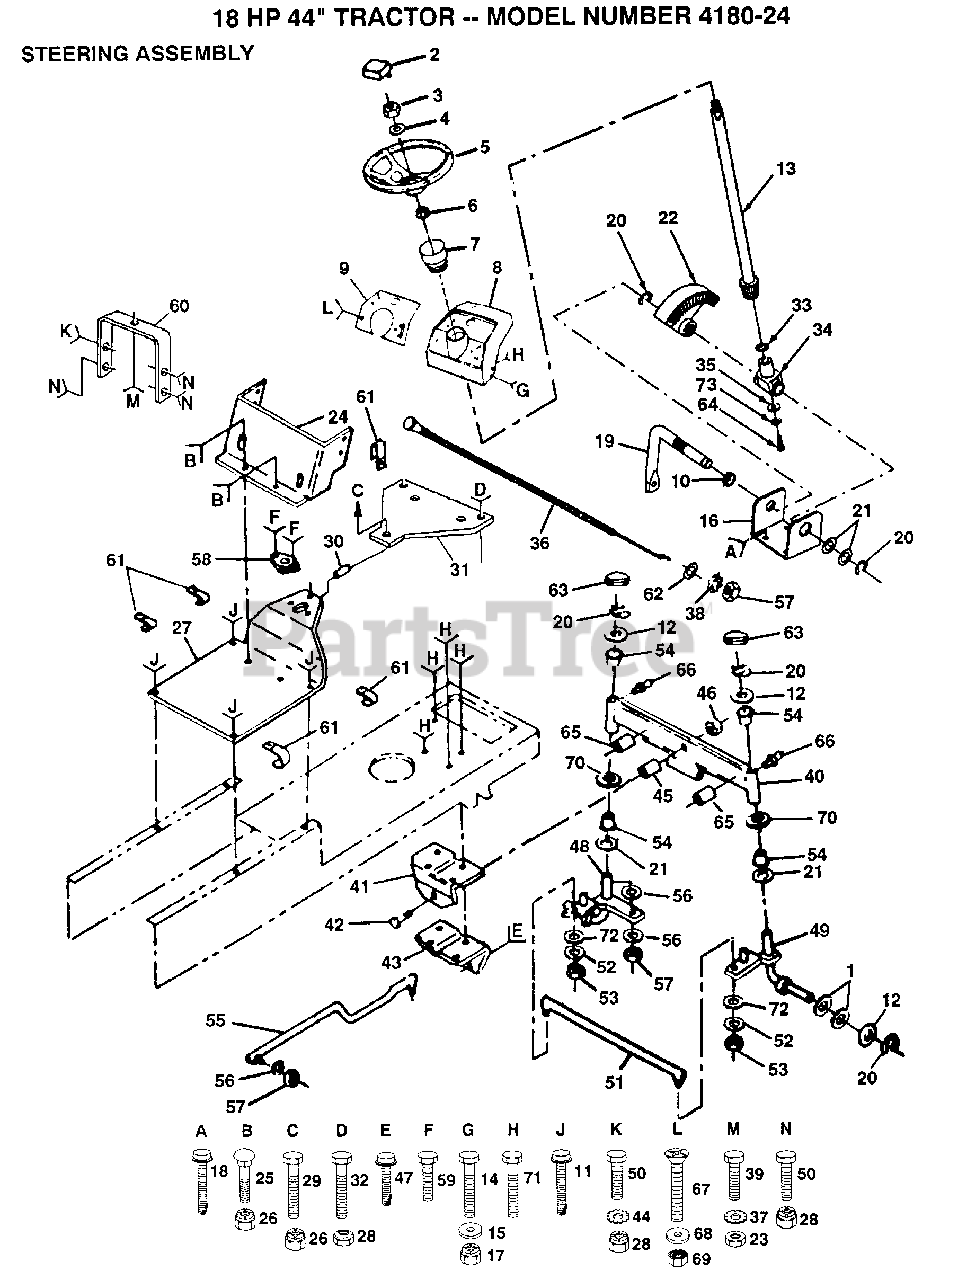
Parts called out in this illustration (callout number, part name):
1	WASHER
2	"INSERT,STR WHEEL"
4	WASHER
6	ADAPTER LT
10	NYLINER T
11	SCREW LT
12	WASHER
14	BOLT
15	WASHER
16	"BRKT,STEERING"
18	SCREW
20	RING
21	WASHER .T
24	LOWER DASH
25	SCREW
29	BOLT
30	SPACER
33	THRUST WASHER
34	SUPPORT.SHAFT
36	CHOKE CONTROL
38	LOCKWASHER
39	BOLT
40	FRONT AXLE
41	SUPPORT-SADDL T
42	BOLT LT
43	SUPPORT.SADDLE.FT
44	LOCKWASHER
45	BEARING
47	SCREW LT
49	SPINDLE ASM RH
51	TIE ROD
52	LOCKWASHER
53	NUT.LOCK.5/16-24
54	COL. SRTG. BEAR.
56	LOCKWASHER
60	SUPPORT ASS'Y
61	CLIP T
62	WASHER
63	CAP
64	"SCREW,SPECIAL"
65	AXLE PIN
66	ZERK M
67	SCREW
68	WASHER
70	WASHER
71	SCREW SPECIAL
72	WASHER M
73	LOCKWASHER
